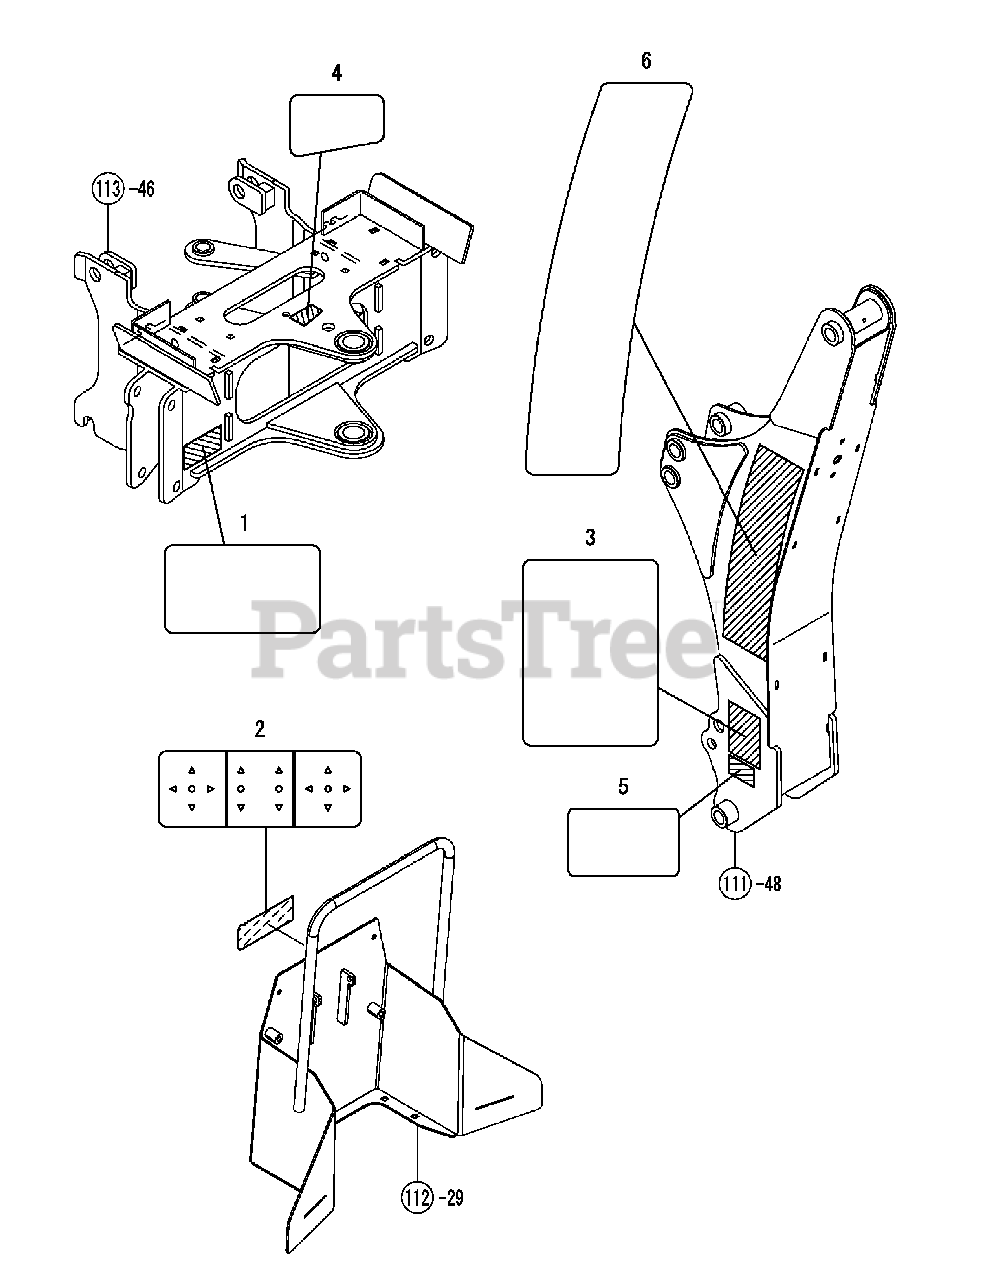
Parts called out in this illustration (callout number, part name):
1	DECAL, SERIAL NUMBER
2	DECAL, OPERATION
3	DECAL, IMPORTANT
4	DECAL, SAFETYLOCK SWING
5	DECAL, SAFETYLOCK BOOM
